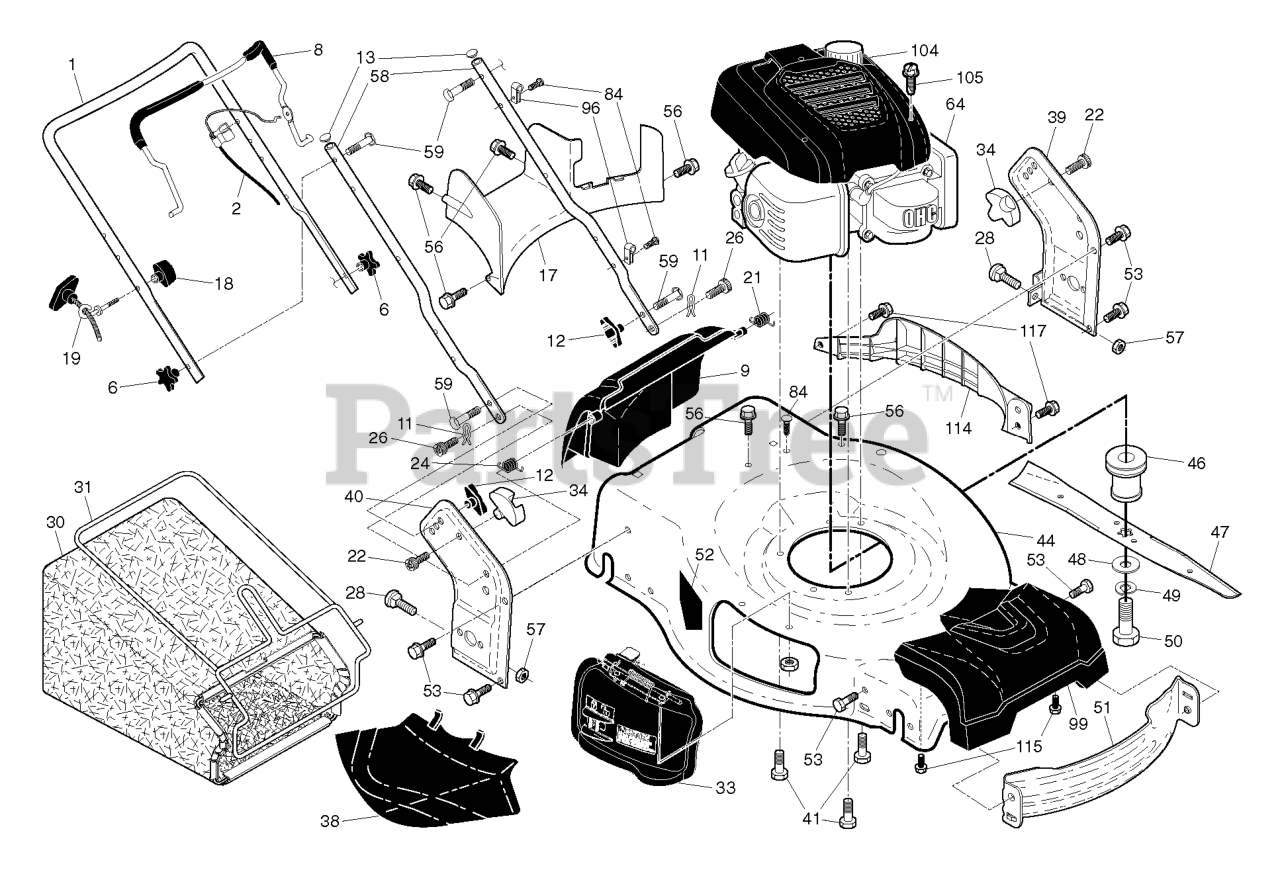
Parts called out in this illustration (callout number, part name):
1	HANDLE.UP.3POS.BS.AW2.GREY
2	CABLE.MZR.ZONE.CONTROL
6	KNOB.HANDLE.PLASTIC.STAR.BLACK
8	BAIL.OM.ERGO.BENT.MZR.ORAN.668
9	DOOR.REAR.ASM.22+.HUSQ.F/RG.CE
11	COTTER.HAIRPIN.DOOR/HANDLE.PIV
12	KNOB, DEFLECTOR
13	PLUG.PLASTIC.7/8".14-20.GAUGE
17	BAFFLE.REAR.22+RGD.AWD.PLASTIC
18	T-KNOB.NEW ROPE GUIDE
19	GUIDE.ROPE.BLK.ZINC.CHROM
21	SPRING.LH.BLACK
22	SCREW.PAN.HEAD.#10
24	SPRING.RH.GRAY
26	SCREW,DOOR/HANDLE.PIVOT
28	BOLT.CARRIAGE.LN.5/16-18X.5/8
30	GBAG.BA85028EM.NOFRAME.GRY/SLV
31	FRAME.GBAG.22+.BLK
33	DOOR ASSY KIT.MULCH DOOR.CE 22
34	BRACKET.GRASSBAG.ATTACHING.BLK
38	DEFLECTOR.CLIPPING.22.BLACK
39	BRACKET.ASM.HANDLE.LT.22+.GREY
40	BRACKET.ASM.HANDLE.RT.22+.GREY
41	BOLT 3/8-16X1-1/8
44	KIT.HSG.22+AW.MC.WO.668.CE SYM
46	ADAPTER.BLADE.25MM.3MPH
47	BLADE.22+4N1.2PIN.5STAR.(P07)
48	WASHER,HARDEN
49	LOCKWASHER
50	SCREW, HEX HD 3/8-24 X 1-3/8
51	BAFFLE.FRONT.22.PLUS
52	DECAL.INTERNATIONL.CUTFINGER
53	BOLT.5/16HEX.WHS.HD
56	SCREW.HX.13X.750
57	NUT.FLANGE.5/16
58	HANDLE.LOWER.22+.BT.GRAY
59	BOLT, HANDLE 5/16-18X1.75
84	FASTENER.PUSH.O.250X0.783
96	CLIP.CABLE.BLK
99	COVER.ASSEMBLY.FRONT.22+AWD
104	SHROUD.ASM.HONDA.HUSQVARNA
105	SCREW.SHROUD.HONDA
114	BUMPER.LEFT SIDE 22+.498
115	SCREW.SHOULDER.5/16X1.375
117	BOLT.HEX.HD.WASHER.5/16-18X.75
